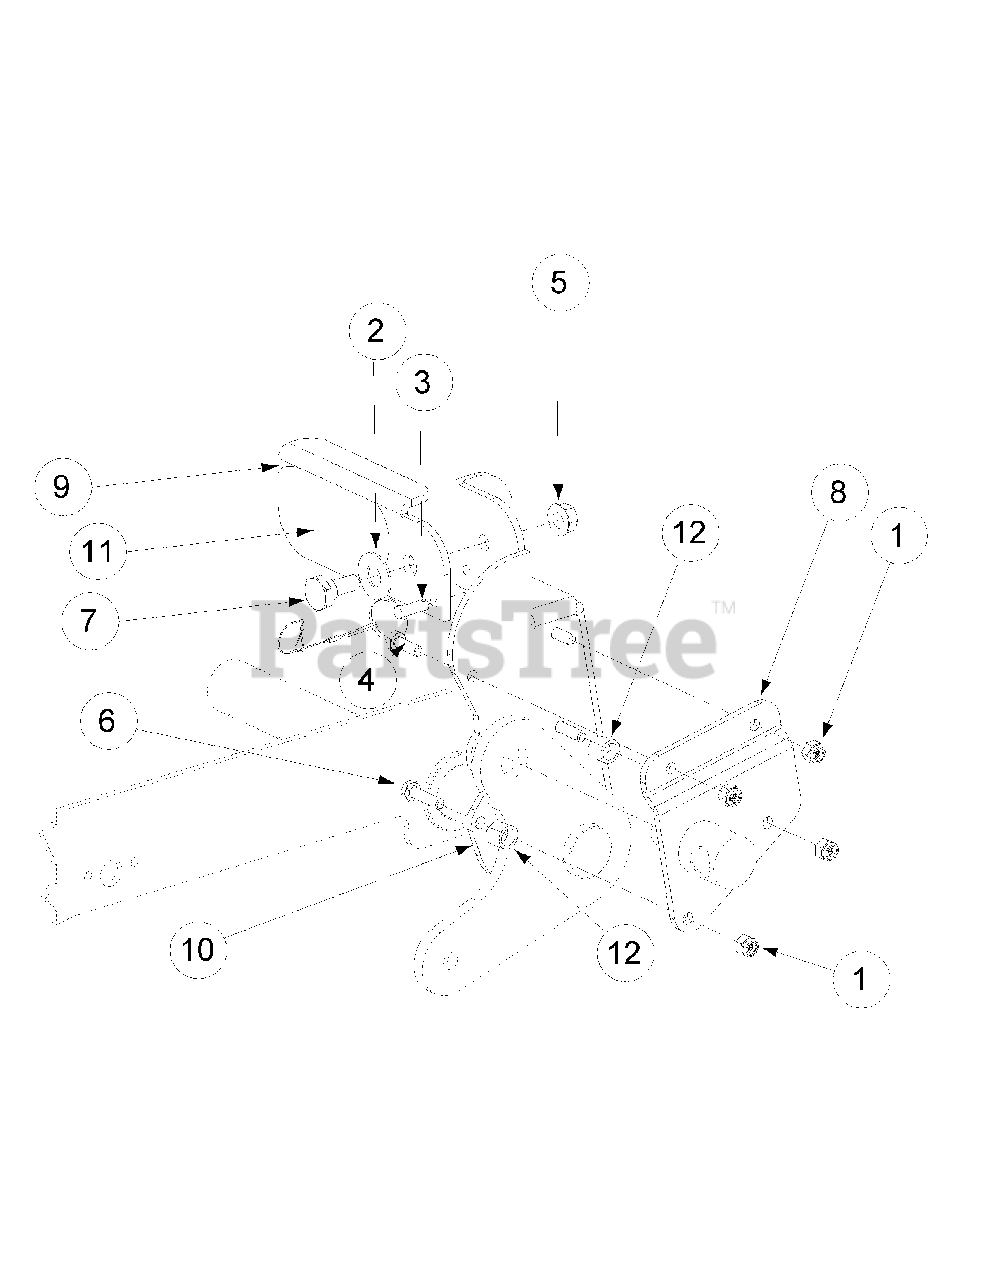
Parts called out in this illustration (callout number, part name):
1	Lock Nut, Nylon Insert, 1/4-20
2	Washer, 1/2 x 1 Shim
3	Detent Pin w/Lanyard, 1/4"
4	Hex Cap Screw, 1/4-20, .75
5	Hex Nut, Flange Lock 3/8-16
6	Hex Cap Screw, 1/4-20, 1.00
7	Shoulder Screw, .50x.27 Lg., 3/8-16
8	Foot Lift Backup Pedal
9	Deck Foot Pedal Lift
10	Deck Foot Pedal Lift Holder
11	Deck Foot Lift Pad
12	Turnbuckle Sleeve
